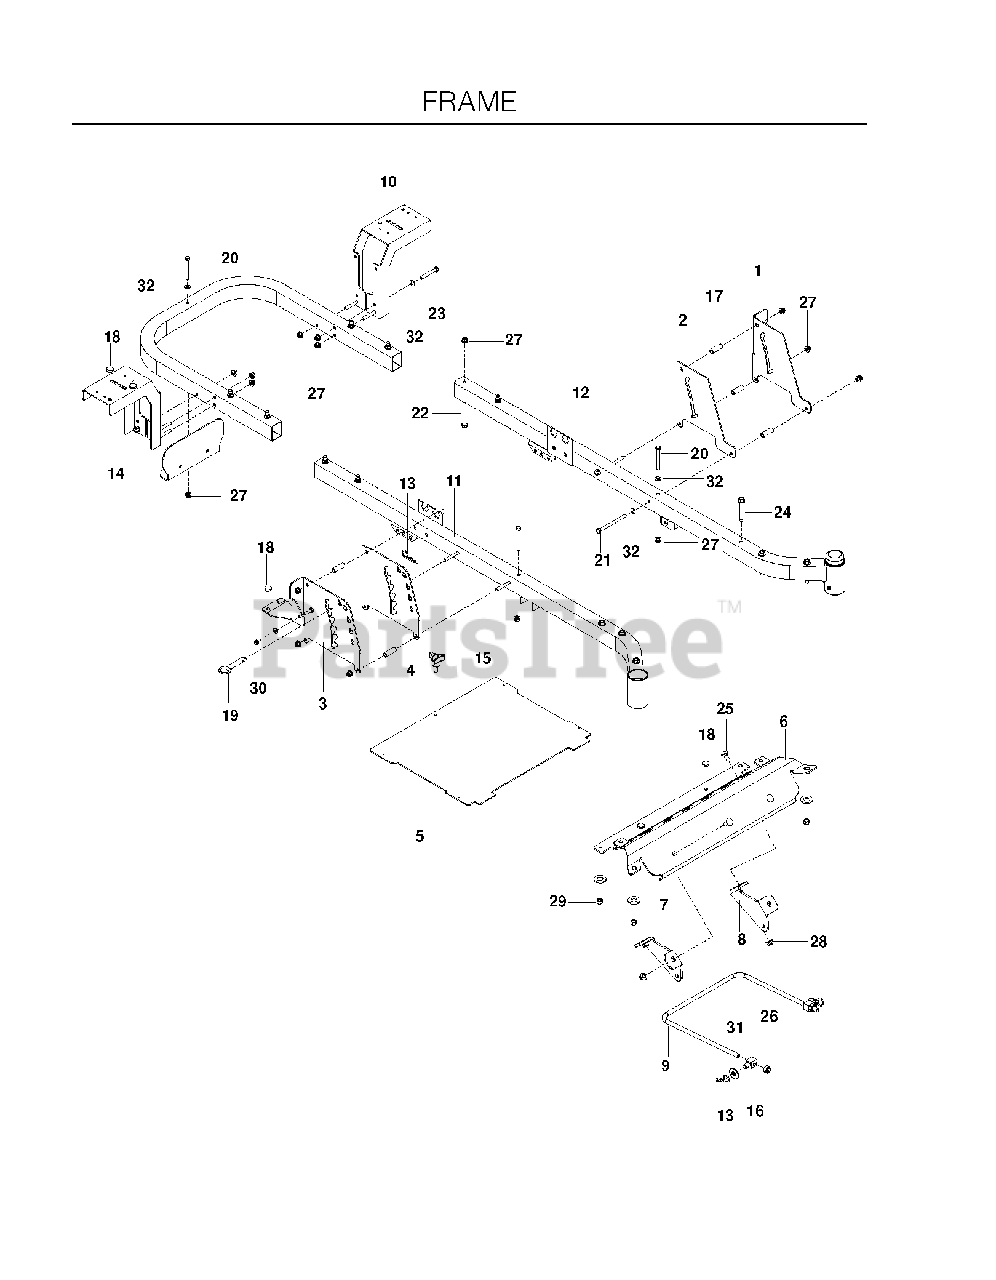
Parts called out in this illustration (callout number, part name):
1	PLATE, OUTER BRAKE, BLACK
2	PLATE, BRAKE LATCH, BLACK
4	PLATE, DECK HEIGHT, BLACK
5	PLATE, FOOT W/DECALS SPZ
6	FOOT REST, MED BLUE
7	MOUNT, STRUT, RT, BLK
8	MOUNT, STRUT, LT, BLK
9	LINK, FRONT SUSP.
10	SUPPORT, FENDER, BLACK
11	FRAME, RT, BLUE
12	FRAME, LT, BLUE
13	HAIRPIN #4
14	PLATE, HITCH BLU
15	KNOB W/STUD
17	SPACER, .334 ID X .5 OD X 1.5
18	GROMMET, BUMPER
19	HITCH PIN
20	HCS 5/16C X 2-3/4
21	HCS 5/16C X 4
22	HCS 3/8C X 3
23	CAPSCREW
24	ENGINE BOLT, SPECIAL
25	RHSNB 3/8C X 1
26	7/16-14 HEX NUT W/NYL RING ZD
27	5/16-18 NYLOC FLANGE NUT
28	NUT 3/8-16 HEX FLG NYLOC ZD
29	NUT HEX 3/8-16 NYLON, THIN
30	NUT 1/4-20 NYLOC
31	WASH USS FLAT 1/2
32	FLAT WASHER 5/16 SAE
